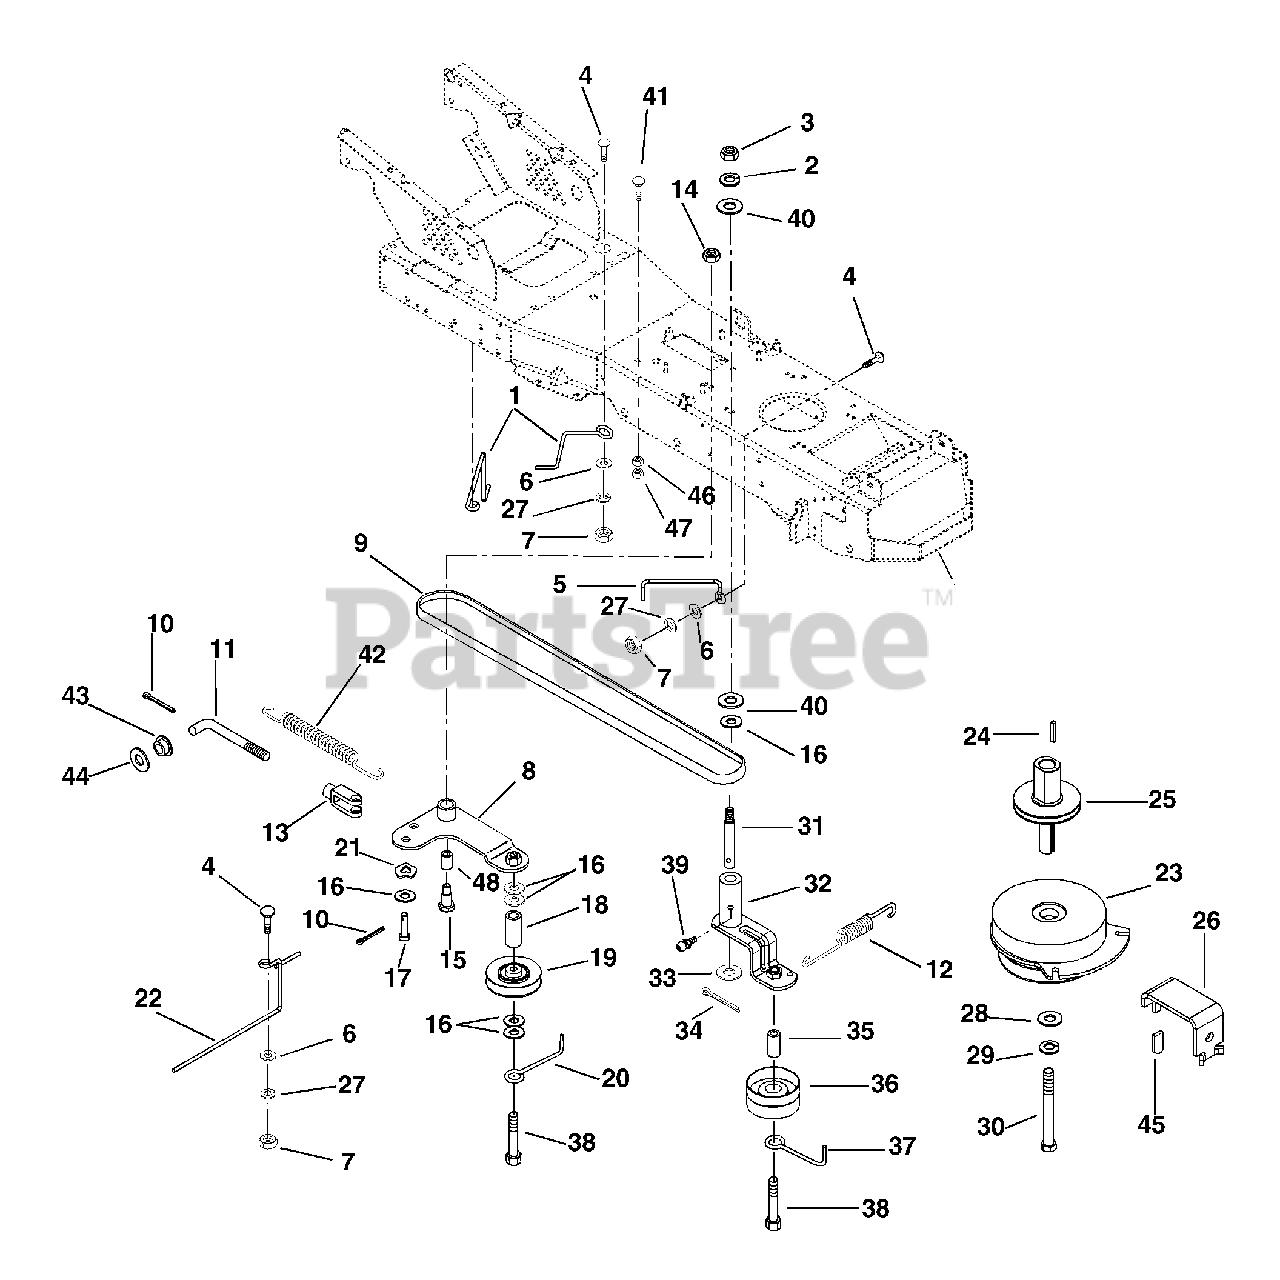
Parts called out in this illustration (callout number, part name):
1	BELT FINGER
2	@WSHR-LK .38X.094 REG YWZC
3	@NUT-HEX .38-16 YWZC
4	BLT-RDHDSQSHK.31-18X.75 GR2 YW
5	BELT FINGER
6	@WSHR-FL-STL.344X.688X.065YWZC
7	@NUT-HEX .31-18 YWZC
8	IDLER PIVOT ARM
9	V-BELT, 4L-WRAPPED
10	@PIN-CTR .09X.75 EXTPRSQCT YWZ
12	SPRING, EXT
13	YOKE, .312-24 X 2.25
14	@NUT-LK-CTR .38-16 YWZC
15	BLT-SHLDR .38-16X1.25
16	WSHR-FL-STL .390X.75X.125 YWZC
17	PIN-CLEV .312X.822 HDND PL
18	TUBE .380 X .625 X 1.360
19	IDLER-V 3X.38
20	FINGER - BELT
21	WAVE WASHER .531X.781X.125FH
22	BELT FINGER - CENTER
23	CLUTCH, ELECTRIC - WARNER
24	KEY-SQ .25 X 1.25 X .25 SAE
25	SHAFT, EXTENSION
26	ANCHOR, CLUTCH
27	WSHR-LK .312X.097 HVY YWZC
28	WSHR-FL-STL.463X1.375X.25 YWZC
29	WSHR-LK .438X.133 HVY YWZC
30	BLT-HEX .44-20X5.50 GR5 YWZC
31	SHOULDER STUD
32	ARM - IDLER PIVOT
33	WSHR-FL-STL .52X.827X.062 YWZC
34	@PIN-CTR .18X1.25 EXTPRSQCT YZ
35	TUBE .380 X .625 X 1.620
36	IDLER, FLAT 3.25 X .38
37	FINGER - BELT
38	@BLT-HEX .38-16X3.50 GR5 YWZC
39	FTG-LUBE .25-28X.256 YWZC
40	@WSHR-FL-STL.438X1.00X.083 YWZ
41	BLT-RDHDSQNK .31-18X1.0 SHTYZ
42	SG-TENS .105X.85X5.00 WLD 40
43	BSHG-FLG .320X.620X.312 NY
44	WSHR-FL-STL .505X.880X.072 YWZ
45	GRIP .062 X .375 X 1.000 RE
46	@NUT-LK-NYL .312-18 YWZC
47	@NUT-LK-CTR .31-18 YWZC
48	BSHG-SLV .328X.50X.75
